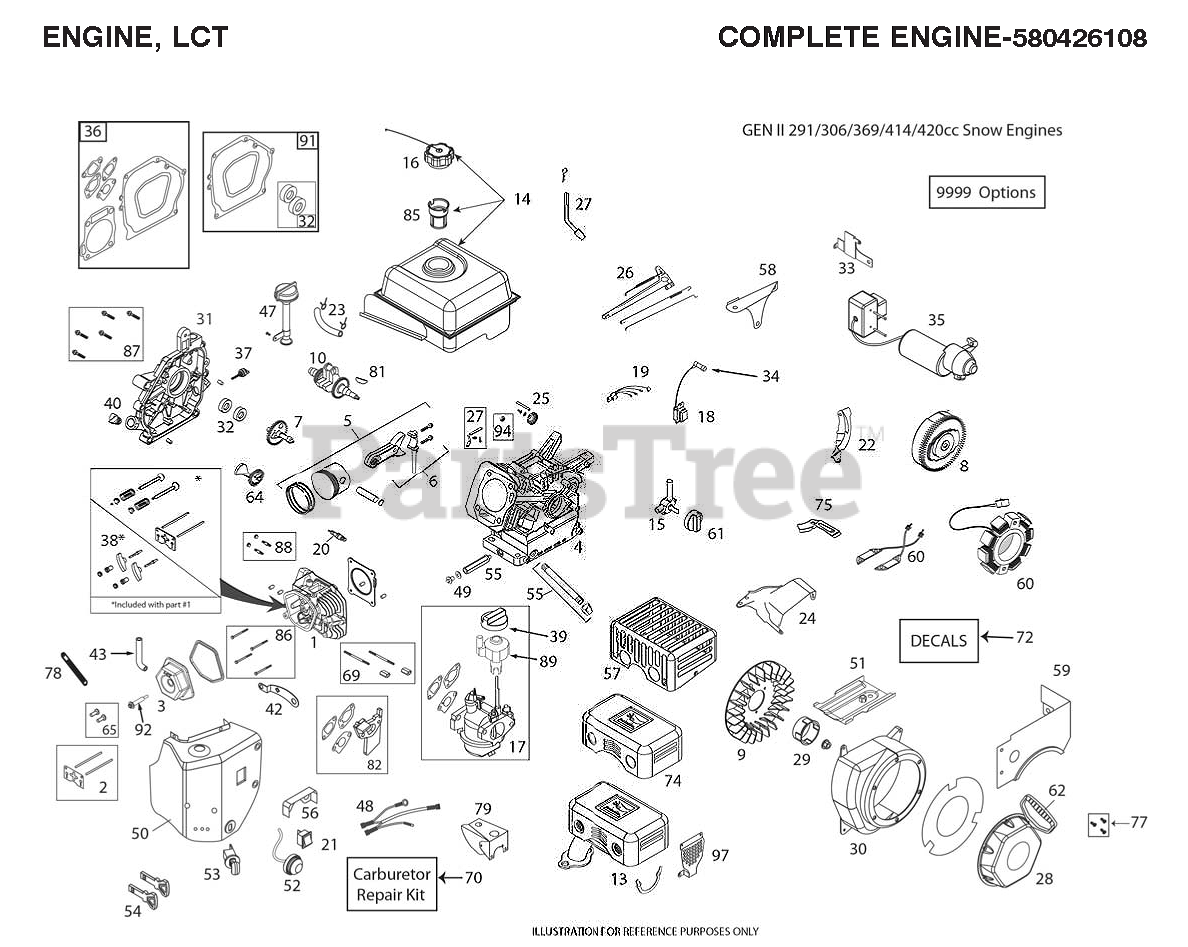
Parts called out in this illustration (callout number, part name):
1	CYLINDER.HEAD.ASSY(SK2911000)
2	PUSH ROD TAPPET KIT
3	VALVE.COVER.LCT.414CC.
4	CYLINDER ASSY SNO.LCT
5	PISTON.AND.ROD.ASSY(SK2911400)
6	CONNECTING ROD ASSY SNO.LCT
7	CAMSHAFT.LCT.291CC
8	FLYWHEEL.EL.ST.SKSNO2401.1
9	FLYWHEEL.FAN
10	CRANKSHAFT
13	MUFFLER ASSY LCT SNO
14	FUEL TANK ASSY - SNOW (291CC)
15	FUEL.PETCOCK.SNOW(SKSN4900)
16	FUEL.TANK.CAP.SNOW(SKSN4301)
17	CARBURETTOR LCT
18	COIL.IGN.CDI.SKSN2403.1
20	SPARK.PLUG(SK2911550)
21	ON/OFF.SWITCH.SNOW(SKSN4403)
23	FUEL HOSE KIT
24	TOP.SHIELD.LCT.
25	GOVERNOR.GEAR.ASSY(SK2912900)
26	GOVERNOR.ARM.ASSY.(SKSN2502)
27	GOVERNOR.SHAFT.(SK2913100)
28	STARTER RECOIL.291/306CC.LCT
29	STARTER CUP.LCT.291/306CC
30	BLOWER HOUSING.LCT.291/306CC W
31	CRANKCASE.COVER.ASY(SK2913600)
32	OIL.SEAL.KIT(SK2913900)
33	SWITCHBOX BRACKET ES LCT 291 S
34	SPARK.PLUG.BOOT.SNW,SKSN4691.1
35	STARTER, ELECTRIC, 230V
36	ENGINE.GASKET.KIT(SK2914300)
37	DIPSTK.OIL.BLK.LCTSK4143711.1
38	ROCKER ARM KIT
39	CHOKE.KNOW.SNOW(SKSN4500)
40	NONREMVABLE.OIL.PLUG(SK4143715
42	CDI.BOX.BRKT.SNOW(SKSN4402)
43	BREATHER TUBE LCT 291/369/414
47	HIGHOIL.FILL.ASSY.KIT(SKSN4911
48	WIRE.HARNESS(SKSN4406)
49	KIT.OIL.DRAIN.PLUG(SK2089911
50	HEATER.BOX.ASSY.SNOW(SKSN2100)
51	SHIELD.CYLINDER.SNOW(SK4141010
52	PRIMER.BULB.ASSY(SKSN4304)
53	KEY.SWITCH.ASSY.SNOW(SKSN4401)
54	KEY SET(2 KEYS) SKSN0407.1
55	OIL PIPE DRAIN EXTENDED.LCT SK
56	SHIELD.VAPOR(SKSN4606)
57	MUFFLER GUARD.CE.LCT
58	GOVERNOR.LINK.SHIELD(SKSN2501)
59	FUEL TANK SKIRT.LCT.291/306CC
60	ALTERN.60WATT.SKSN2402.1
61	FUEL KNOB-SNOW
62	HANDLE.RECOIL.DELUXE.LCT
65	TAPPET KIT.LCT.SK2911005.1
69	STUD.CARB.MOUTING.KIT.291CC
70	CARBURETTOR REPAIR KIT 291CC/4
74	MUFFLER SHIELD
75	WIRE GUARD
77	BOLT.KIT.RECOIL.LCT.ALL.ENGINE
79	SHIELD CARBURRETOR COVER 414
81	KEYS.FLYWHEEL.136/291CC.5PACK
82	SPACER.CARBURETOR.291CC.LCT
85	STRAINER.FUEL.TANK.LCT.208CC
86	KIT.BOLT.CYLINDER.HEAD.(4PC)
87	KIT.7-BOLT.CRANKCASE.CVR.291CC
88	STUD.MUFFLER.KIT.LCT
89	KNOB LCT.SKSN5325.1 SPEED
91	GASKET KIT CRANKSHAFT.LCT
92	CENTER VALVE COVER BOLT
9999	HIGH.ALTITUDE.JET.6000FT ANDUP
9999	KIT.BOLT.LCT.SK9990.1
